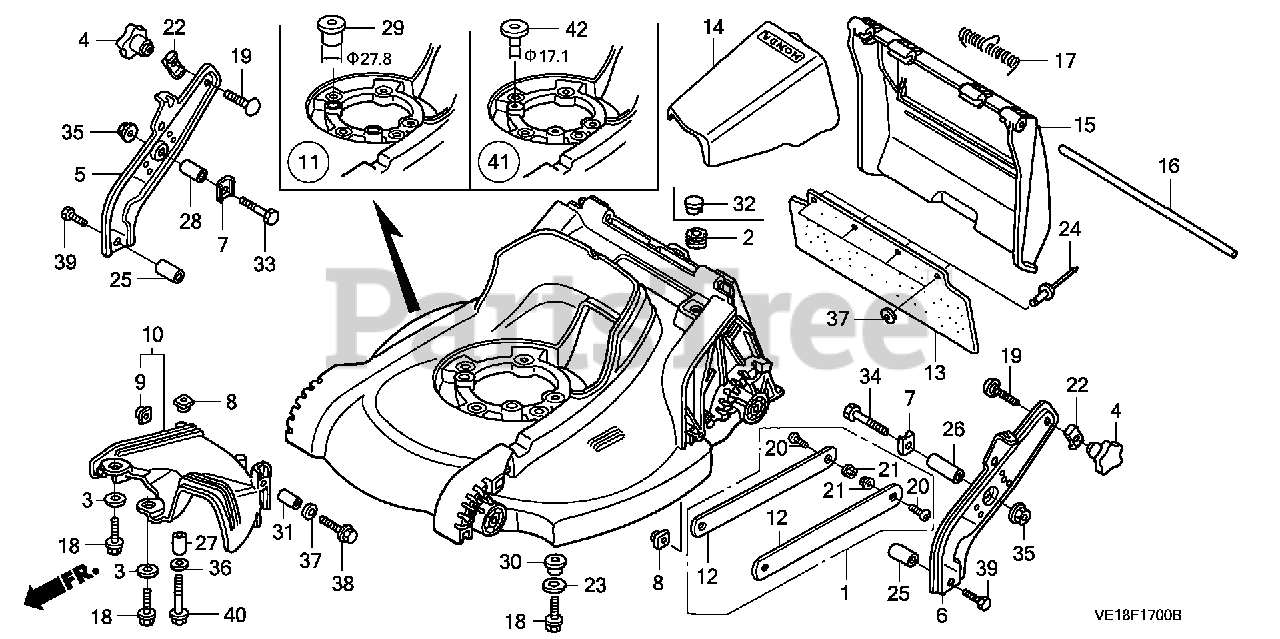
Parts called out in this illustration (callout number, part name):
1	GUARD KIT, HOUSING
2	RUBBER, BATTERY BOX MOUNTING
3	PLATE, HANDLE SETTING
4	GRIP, HANDLE JOINT (UPPER)
5	STAY, R. HANDLE *NH105* (MAT BLACK)
6	STAY, L. HANDLE *NH105* (MAT BLACK)
7	HOLDER, HANDLE STAY
8	NUT, HEADLIGHT SETTING
9	NUT, SPECIAL (6X7)
10	GUIDE ASSY., SCROLL *NH246* (LOOSY GRAY)
11	HOUSING, CUTTER *NH246* (LOOSY GRAY) (VERIFY COLLAR SIZE TO SEE IF THIS FITS--SEE ILLUSTRATION.)
12	GUARD, HOUSING (N/A: USE P/N 06761-VE2-000)
13	SHIELD, RR.
14	STUFFING *NH105* (MAT BLACK)
15	GUARD, DISCHARGE
16	SHAFT, DISCHARGE GUARD
17	SPRING, GUARD RETURN
18	BOLT, ENGINE SETTING
19	BOLT, PAN (8X35)
20	SCREW, HOUSING GUARD (N/A: USE P/N 06761-VE2-000)
21	NUT, FLANGE (N/A: USE P/N 06761-VE2-000)
22	WASHER, FRAME JOINT
23	WASHER, ENGINE MOUNTING
24	RIVET (6MM)
25	COLLAR, STAY (LOWER)
26	COLLAR, L. STAY (UPPER)
27	COLLAR, HANDLE
28	COLLAR, R. STAY (UPPER)
29	COLLAR A, BED
30	COLLAR B, BED
31	COLLAR, SCROLL
33	BOLT, HEX. (8X40)
34	BOLT, HEX. (8X55)
35	NUT, FLANGE (8MM)
36	WASHER, PLAIN (8MM)
37	WASHER, PLAIN (6MM)
38	BOLT, FLANGE (6X35)
39	BOLT, FLANGE (8X22)
40	BOLT, FLANGE (8X45)
